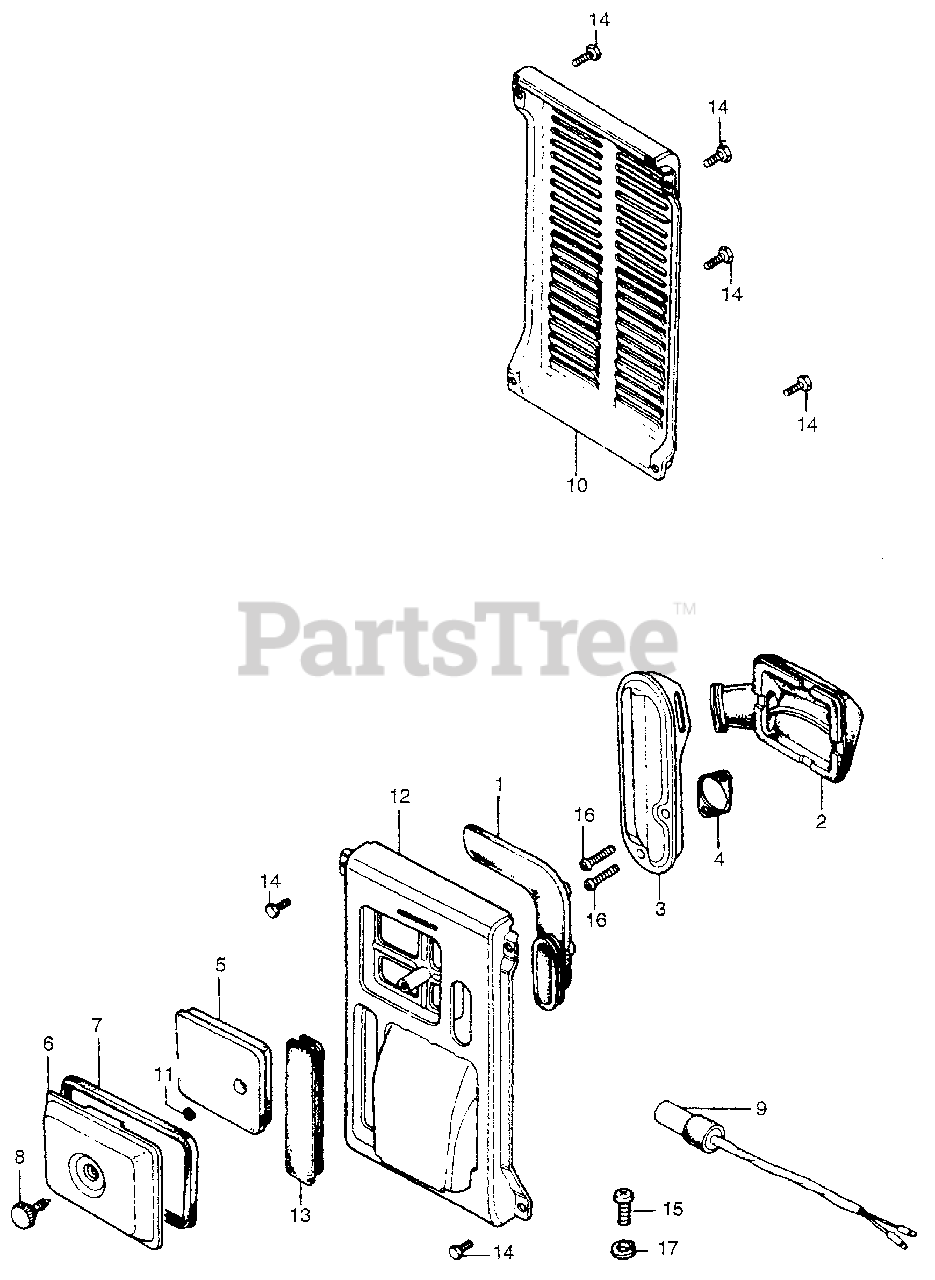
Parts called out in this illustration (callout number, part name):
1	TUBE, AIR CLEANER (NOT AVAILABLE)
2	TUBE, IN. MUFFLER CONNECTING (NOT AVAILABLE)
3	MUFFLER, IN. (NOT AVAILABLE)
4	GASKET, IN. MUFFLER (NOT AVAILABLE)
5	ELEMENT, AIR CLEANER
6	COVER, AIR CLEANER *R18* (DAYTONA ORANGE) (NOT AVAILABLE)
7	RUBBER, AIR CLEANER SEAL (NOT AVAILABLE)
8	LATCH, COVER (NOT AVAILABLE)
10	COVER, R. SIDE *R18* (DAYTONA ORANGE) (NOT AVAILABLE)
11	STOPPER, LATCH (NOT AVAILABLE)
12	COVER, L. SIDE *R18* (DAYTONA ORANGE)
13	GROMMET, CHOKE (NOT AVAILABLE)
14	BOLT, HEX. (5X10)
15	SCREW, PAN (5X8)
16	SCREW, PAN (5X20)
17	WASHER, SPRING (5MM)
